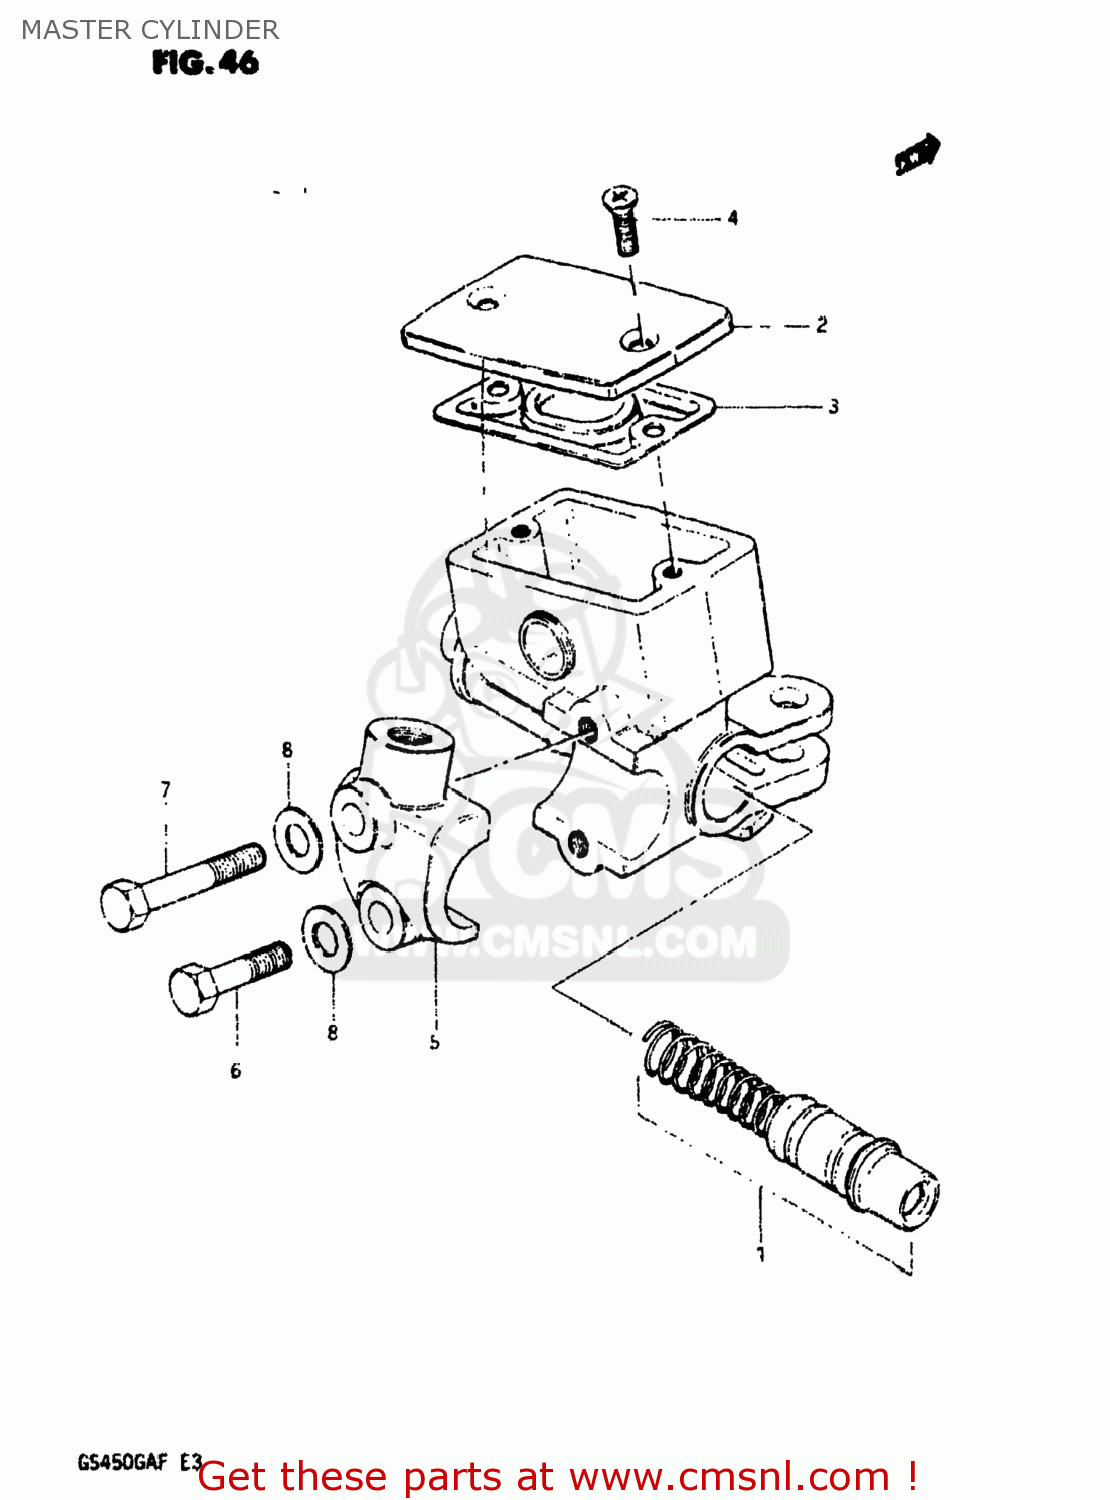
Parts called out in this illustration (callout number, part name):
1	PISTON & CUP SET
2	CAP
3	4
4	SCREW
5	HOLDER
6	BOLT
7	BOLT
8	WASHER
